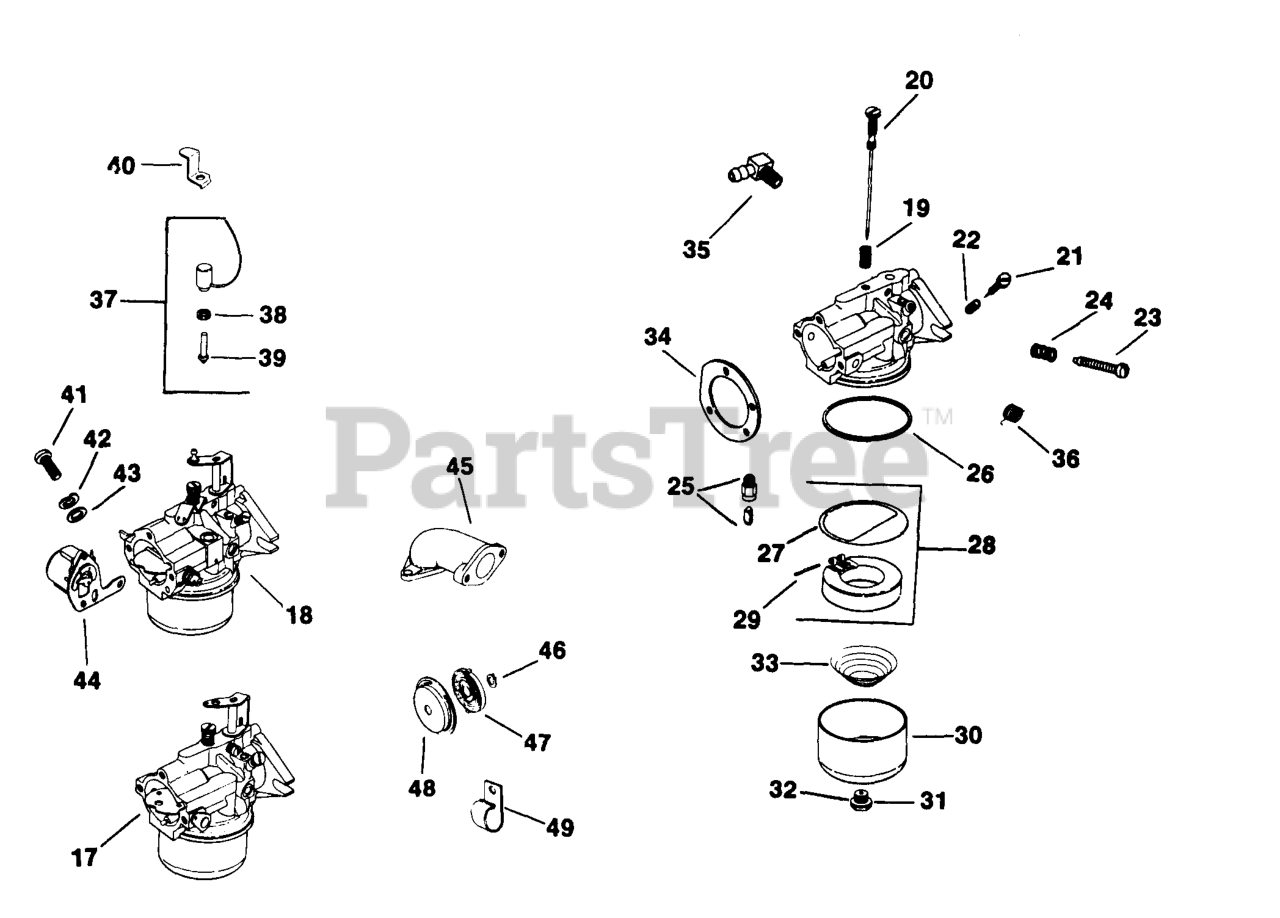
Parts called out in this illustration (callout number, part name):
20	NEEDLE - DISCONTINUED
22	SPRING-(#DSC)
23	SCREW, SPECIAL
25	Needle and Seat
28	KIT, FLOAT REPAIR - DISCONTINUED
31	NUT - DISCONTINUED
2575702-S	KIT, CARBURETOR REPAIR
